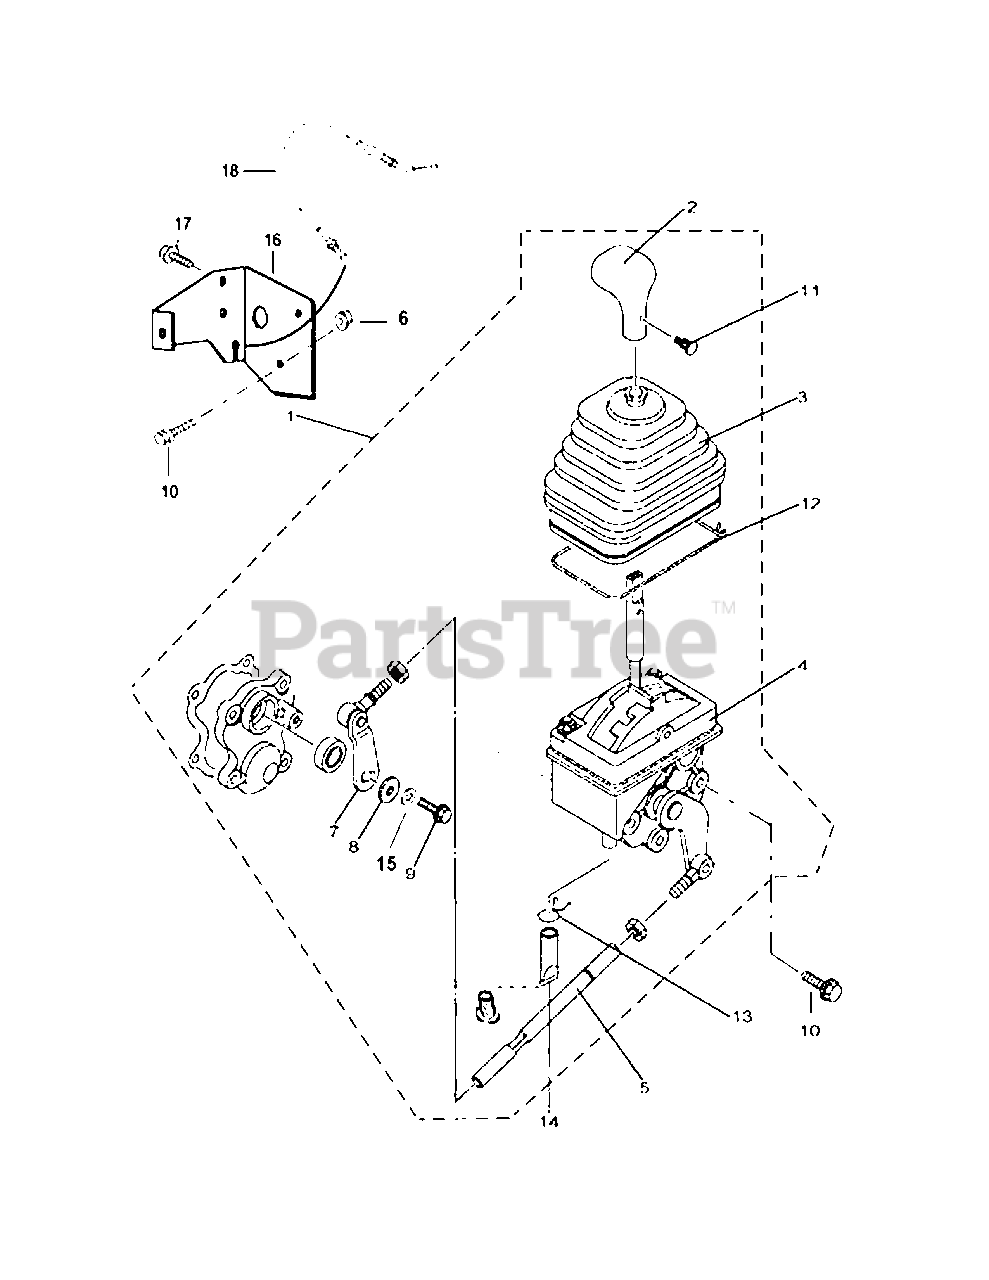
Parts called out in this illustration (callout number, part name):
1	Gear Shifter Assembly
2	Gearshift Knob
3	Gearshift Boot
4	Gearshift Assy
5	Gear Shift Rod
7	Gearshift Tie Assy
8	Washer 6×18×1.6
9	Hexagon Flange Bolt M6×16
10	Hexagon Flange Bolt M8×16
11	Plastic Screw
12	Rubber Cover Clamp
14	Water Leakage Pipe Cap
15	Spring Washer -6
16	Gear Shifting Support
17	Hexagon Flange Bolt M6×12
18	Reverse Cable
